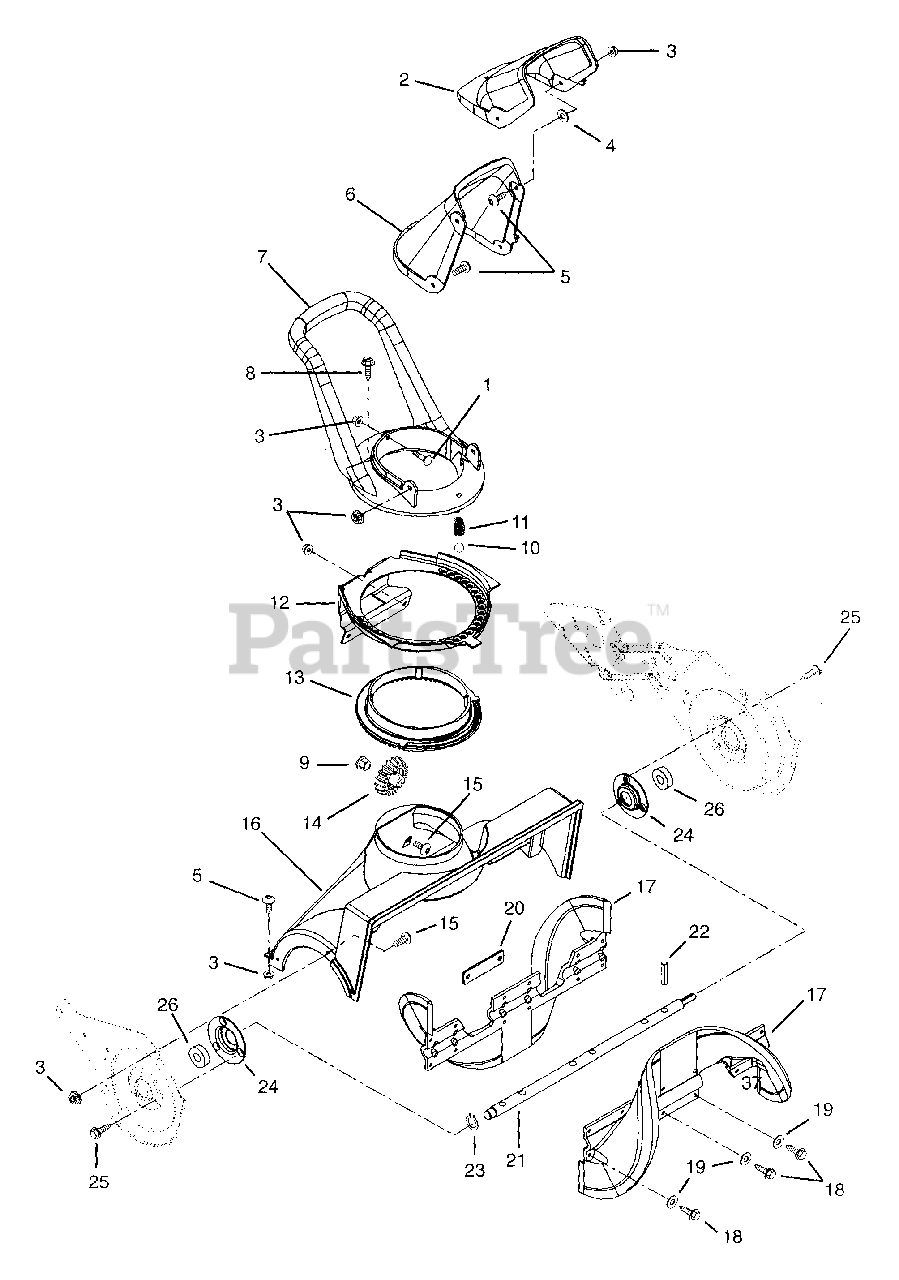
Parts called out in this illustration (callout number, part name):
1	@BLT-RDHDSQNK .25-20X.75 G5YZ
2	DEFLECTOR-DISCHARGE CHUTE ASSY
3	NUT-LK-FLG .250-20 PL BLK
4	WSHR-FL-RBR .31X1.25X.06
5	SCR-MCH .25-20X.75 TXTR YWZC
6	CHUTE-DISCHARGE
8	SCR TAP 8-18X1.50 SL HWH PL B
9	BSHG-FLG .325X.444X.440X.560
10	BALL .375 GRD 2000 CBN STL
11	SG-COMP .045X.360X1.75 WLD12.5
12	BRKT-DISCHARGE CHUTE ROTATION
13	GEAR-DISCHARGE CHUTE SEGMENT
14	PINION-DISCHARGE CHUTE 18T
15	SCR-MCH .25-20X.50 TXTR PL
16	HOUSING-IMPELLER ASSY
17	IMPELLER HALF
18	@SCR-TAP .25-20X1.00 HWH TR YZ
19	WSHR-FL-STL .281X1.000X.063
20	PLATE-BOLT,SELF-TAPPING
21	SHAFT-IMPELLER
22	PIN-ROLL .250X1.75 ZINC PL
23	RG-RTNG-EXT .672X.035
24	CUP-BRG
25	@SCR-TAP .25-20X.50 HWH TR YWZ
26	BRG-BALL .669X1.575X.47 (6203)
